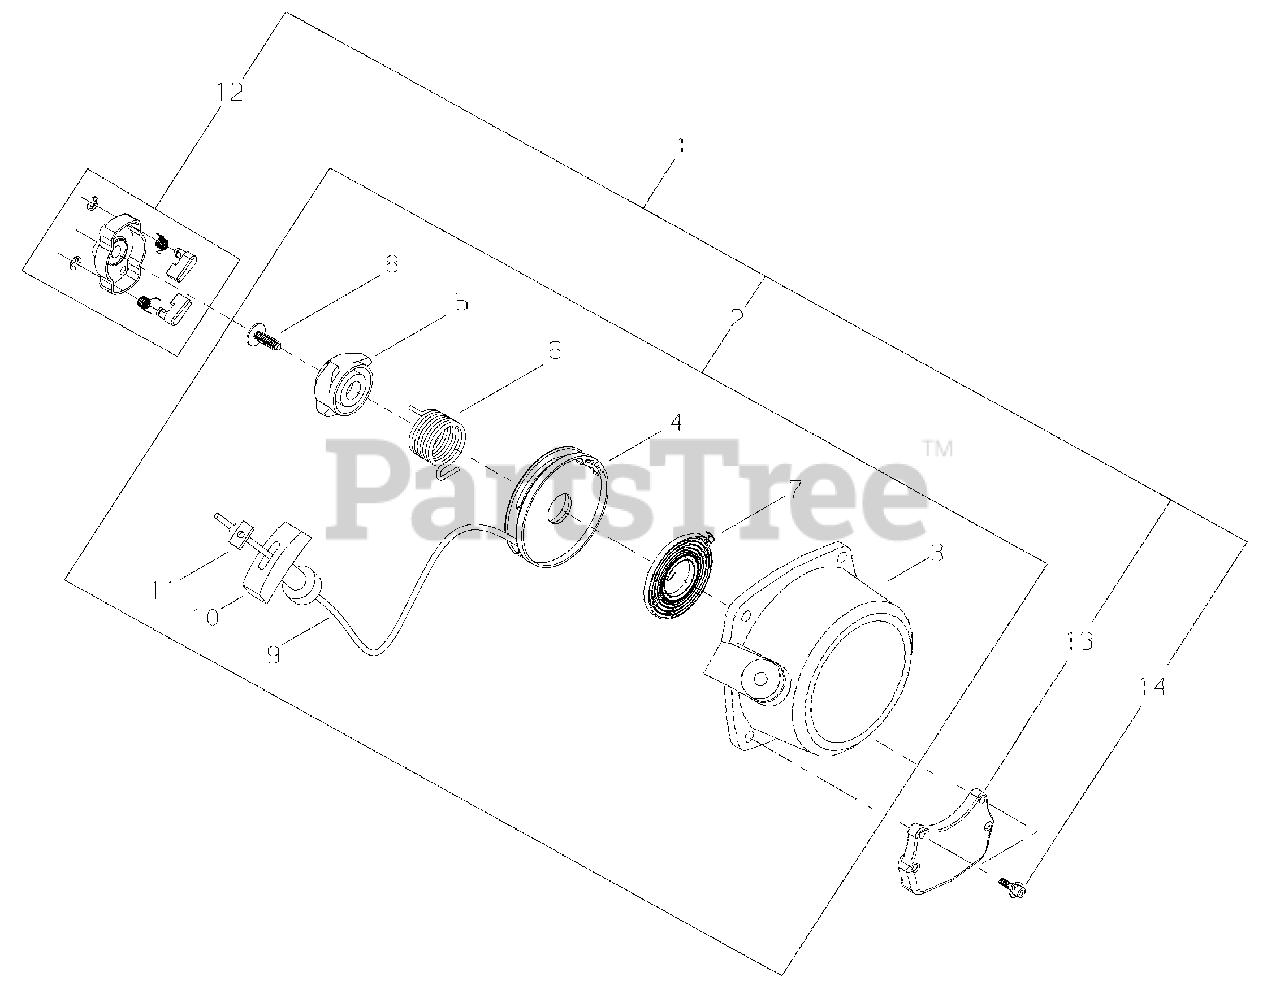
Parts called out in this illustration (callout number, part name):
1	STARTER KIT
2	STARTER ASSY
3	CASE, STARTER
4	REEL, ROPE
5	CAM
6	SPRING
7	SPRING, REWIND
8	SCREW - 5
9	ROPE, STARTER
10	GRIP, STARTER
11	RETAINER, ROPE
12	STARTER PAWL ASSY
13	BRACKET, FUEL TANK
14	SCREW - 4X20
